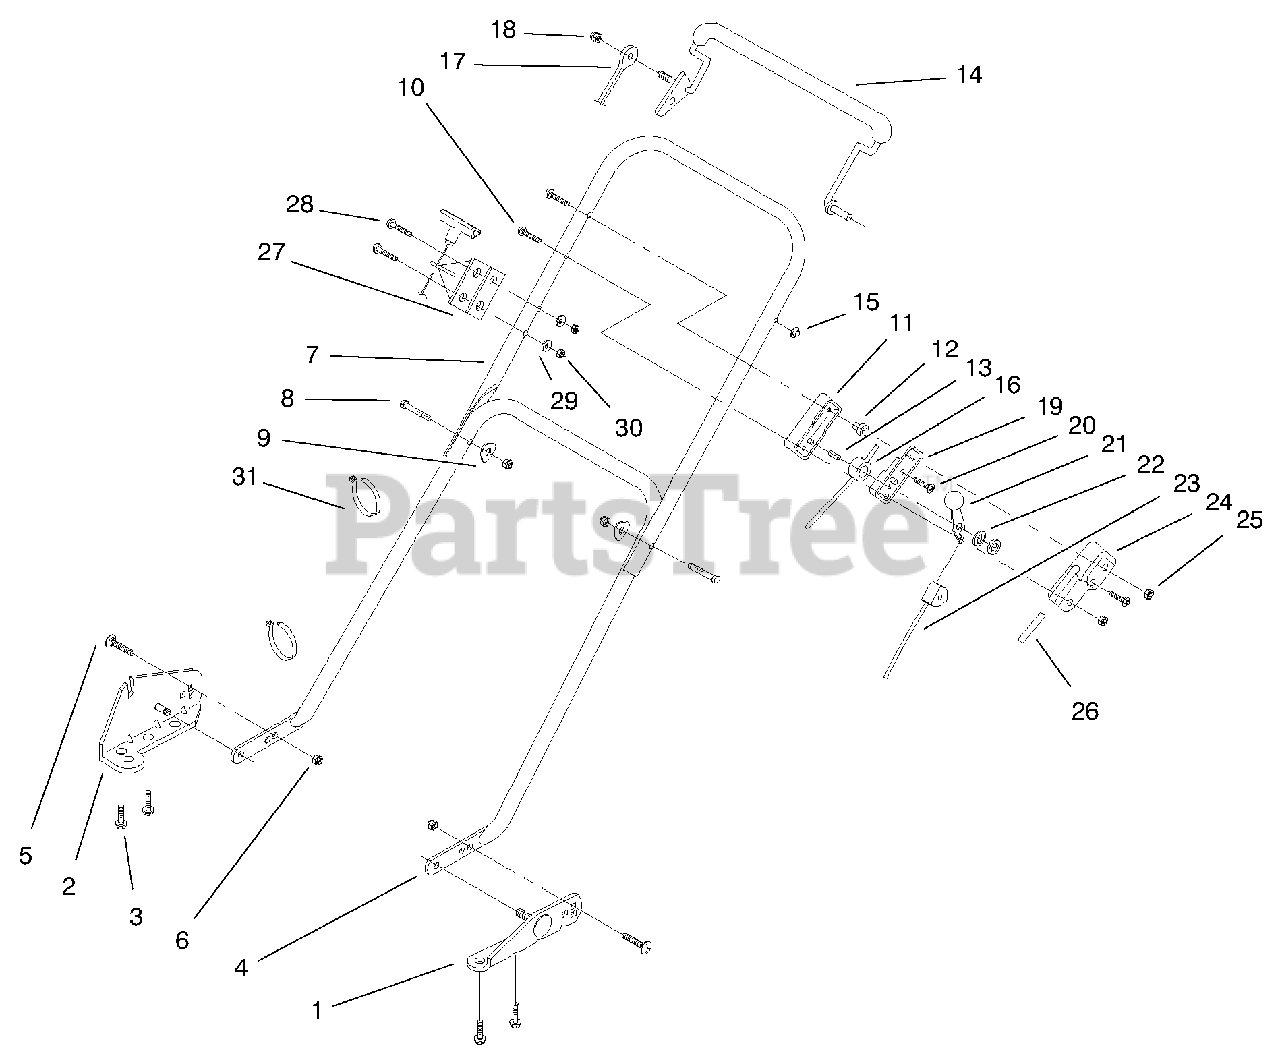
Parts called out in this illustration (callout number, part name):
1	Bracket & Pin Assembly
2	Bracket & Pin Assembly
4	Handle-Lower Section
5	Bolt-Carriage
6	Nut-Lock
7	Handle-Top Section
8	Screw-Hex Hd. Cap
11	Case-Control
14	Lever-Control
15	Nut-Pal
17	Cable-Control
18	Nut-Acorn
19	Case-Control
21	Lever & Knob Assembly
22	Washer-Spring
23	Cable-Throttle
24	Case-Throttle
25	Nut-Lock
26	Decal-Throttle Control
27	Guide-Rope
29	Washer-Plain
30	Nut-Lock
31	Strap-Tie
